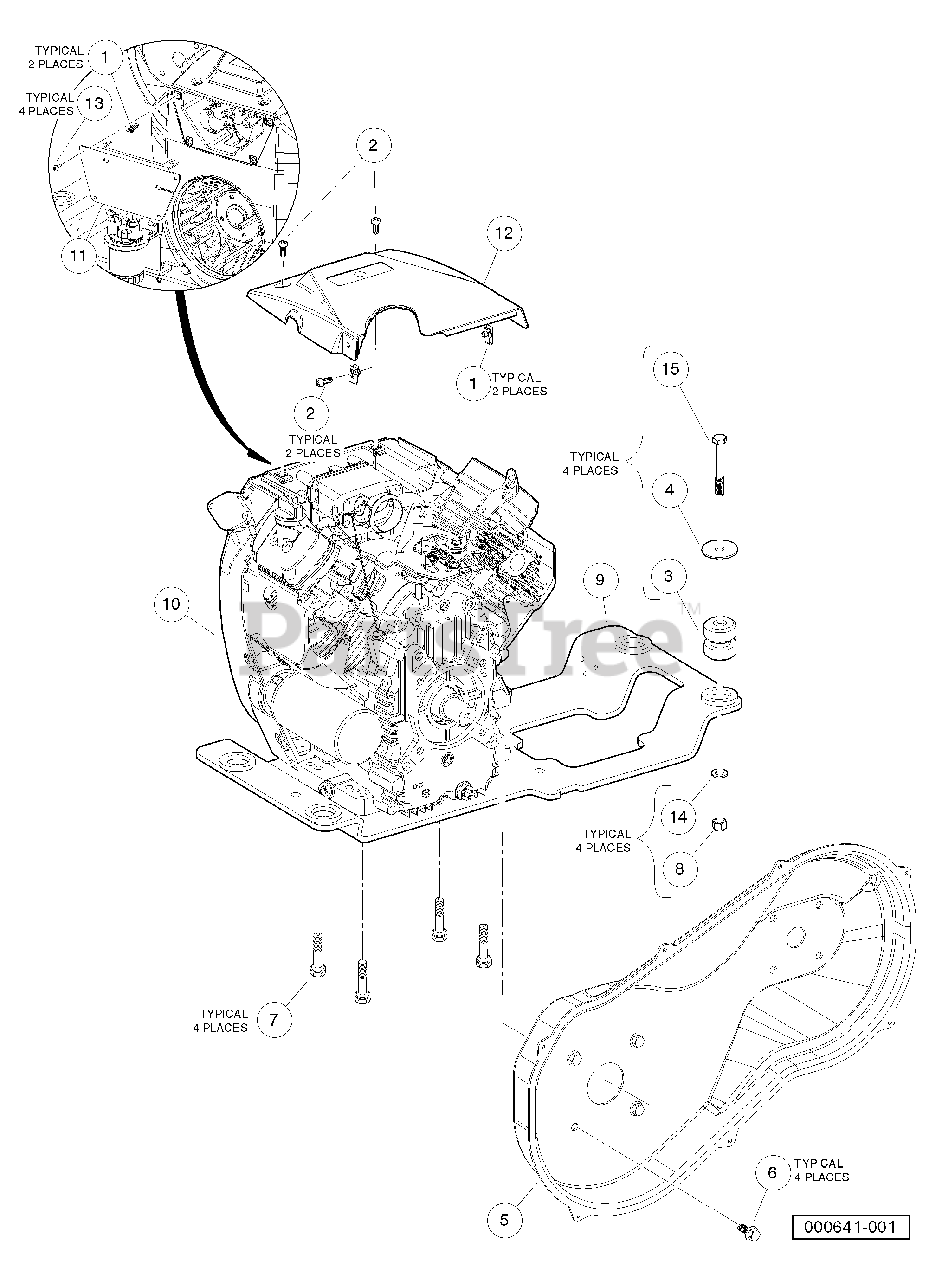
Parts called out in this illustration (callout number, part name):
1	U-nut, M6-1.0 Prev Torque
2	Screw, M6 Torx Bttn Hd Sems
3	Isolator Ring and Bushing
4	Washer, Snubbing, Ring N Bush
5	Cover, CVT Inner, FH680D
6	Bolt Flanged Head, 3/8-16x1.0 with Loctite
7	Bolt, Flange Head, M10x 1.5 X 40 with Loctite
8	Locknut, M12x1.75 Nylon Insert
9	Weldment, Eng Mnt, Kaw, Fh680d
10	Engine, Kawasaki, FH680D
11	Engine, Front Cover, Fh680d
12	Cover, Engine, Top
13	Screw, Pn Hd Blk, 10-16 X .625
14	Washer, M12 Hard
15	Bolt, M12 X 1.75 X 90
